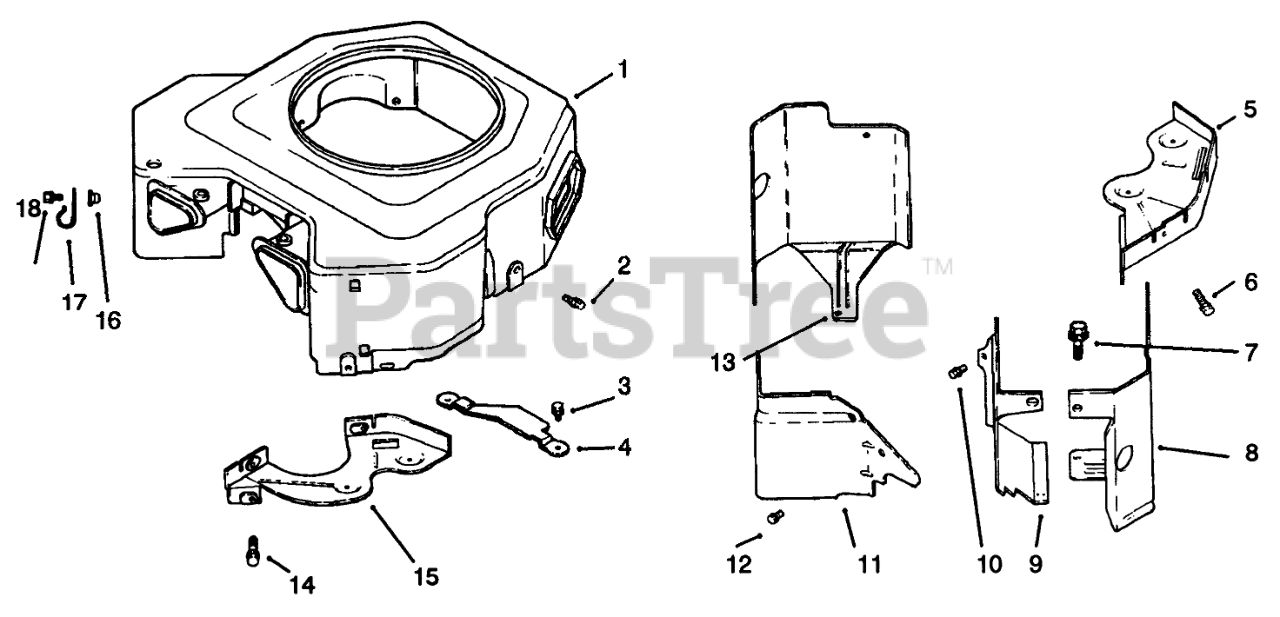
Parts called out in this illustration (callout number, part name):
1	Housing-Blower ASM
3	Screw
4	Guard-Flywheel
5	Plate-Backing #2 side
7	Screw
8	Baffle Cylinder #2 Side
9	Baffle-Valley #1 Side
10	Screw
11	Baffle-Valley #2 Side
13	Baffle Cylinder #1 Side
14	Screw
15	Plate-Backing #1
17	Clamp
